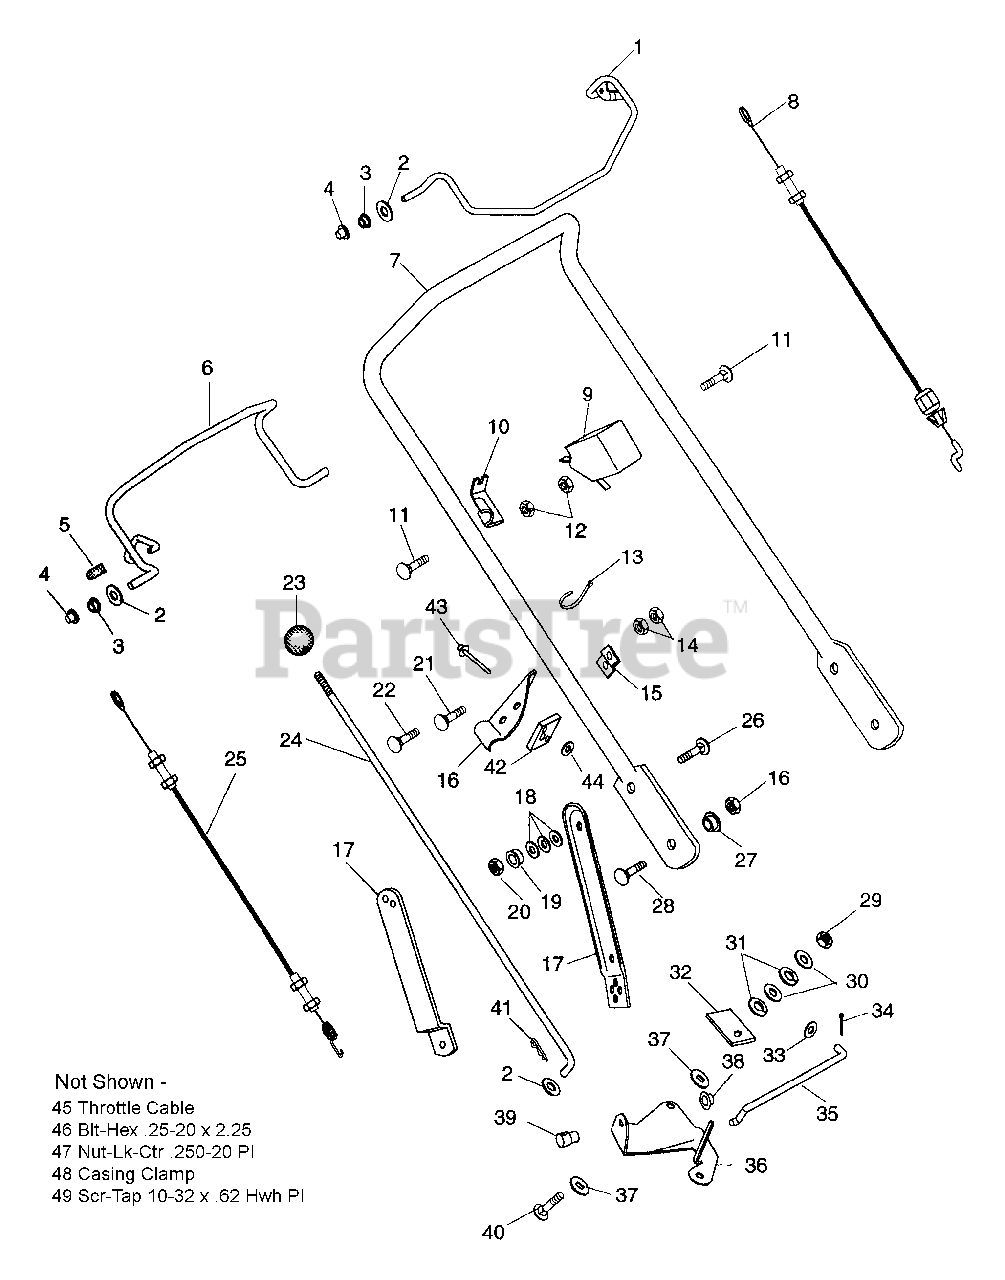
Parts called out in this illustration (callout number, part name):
1	ENGINE BAIL
2	WSHR-FL-STL.344X.688X.065PL
3	BSHG-FLG .325X.444X.440X.560
4	NUT-PUSH .312 DIA. PAL
5	CAP, VINYL, .25 ID
6	TRACTION BAIL
7	HANDLEBAR
8	ENGINE CONTROL CABLE
8	ENGINE CABLE
9	SWITCH-CABLE ANCHOR
10	CABLE ANCHOR
10	CABLE ANCHOR-LH
11	BLT-RDHDSQNK .25-20X1.25 XLGPL
12	NUT-KEPS .250-20
13	CABLE TIE LG 5-1/2
14	NUT-LK-CTR .250-20 PL
15	BRACE-SPEED CONTROL
16	BRACKET-SPEED CONTROL
17	LINK,HANDLE BAR ADJUST LH
17	LINK,HANDLE BAR ADJ RH
17	HANDLEBAR BRACKET
18	WASHER,BELLEVILLE SPRING
19	BSHG-FLG .325X.500X.513X.875
20	NUT-LK-TOP .312-18 GR C PL
21	BLT-RDHDSQNK .25-20X1.38SHT PL
22	@BLT-RHDSSQNK .25-20X.38 G2YZ
23	KNOB, BALL 5/16-18 X 1.5
24	ROD-SPEED CONTROL
25	TRACTION CABLE
26	BLT-RDHDSQNK .31-18X1.12 GR5PL
27	BSHG, FLG .325X.499X.26X.88
28	BLT-RDHDSQNK.31-18X.88 GR5YWZC
29	NUT-LK-CTR .375-16 GR A PL
30	WSHR-FL-STL.406X.812X.065PL
31	WSHR-LK .375X.115 HVY PL
32	PRESSURE FLANGE
33	WSHR-FL-STL.281X.62X.065 PL
34	PIN-COTR .06X.50
35	SHIFT LINK
36	BELL CRANK - SPEED CONTROL
37	FRICTION WASHER
38	CAP, 3/8 ROD YWZC
40	BLT-RDHDSQNK .38-16X1.50 PL
41	PIN-HAIR INT .08X.18X1.18
42	SUPPORT PAD
43	RVT .187X.450 DOME AL BLACK
44	WSHR-FL-STL .194X.492X.047 PL
